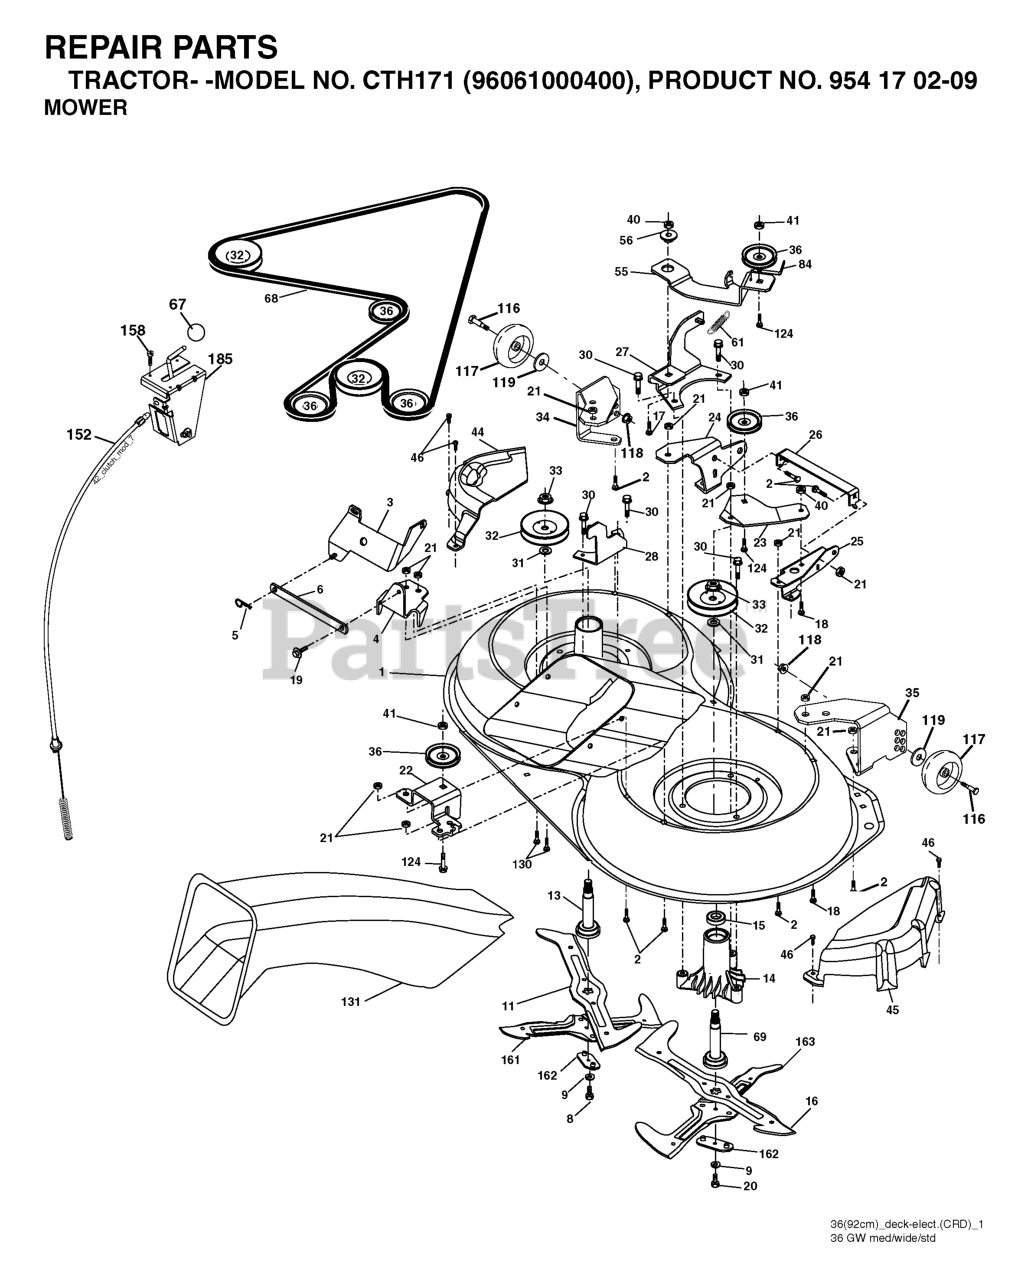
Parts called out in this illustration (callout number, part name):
1	MOWER HOUSING, DECK
2	RP BOLT 5/16-18 X3/4 ZN/YEL GR
5	RETAINER-SPRNG RB
6	BAR.SWAY.92.CRD
8	BOLT.3/8-24X1.25 GR8
9	LOCKWASHER
13	SHAFT ASM VENT
14	HOUSING.MANDREL.VENTED (MACHD)
17	BOLT.3/8-14X1.25
19	BOLT SHD 5/16-18
20	BOLT.3/8-24X1.25GR8. LHTHRD
21	LOCKNUT
26	BRACE.SUPT.SUSP.FRT.CRD
30	SCREW, WASHER HEAD
31	WASHER.SPACER.MANDREL
32	PULLEY, MANDREL
33	NUT, FLG TOPLOCK 9/16"
36	PULLEY.IDLER.4.25
41	NUT LOCK FLG 3/8-16 UNC
45	COVER.MANDREL.RH.CRD
46	SCREW.1/4-20X5/8
56	SPACER.RETAINER.MOWER
61	SPRING.TENSION.BELT
67	KNOB T (3/8 HOLE)
68	HEX-BELT
69	SHAFT.ASM.W/LWR.BRG.RH.THREAD
84	KEEPER, BELT IDLER
116	SHOULDER BOLT
117	RP WHEEL. GUAGE RALLY
118	LOCKNUT
119	WASHER.5/16.FLAT.STE.STD.
124	BOLT.3/8-16X1.50
130	BOLT.CARR.SQNK.5/16-18UNC.X3/4
131	CHUTE BAGGER
158	SCREW
185	HEAD ASM. CABLE CLUTCH
